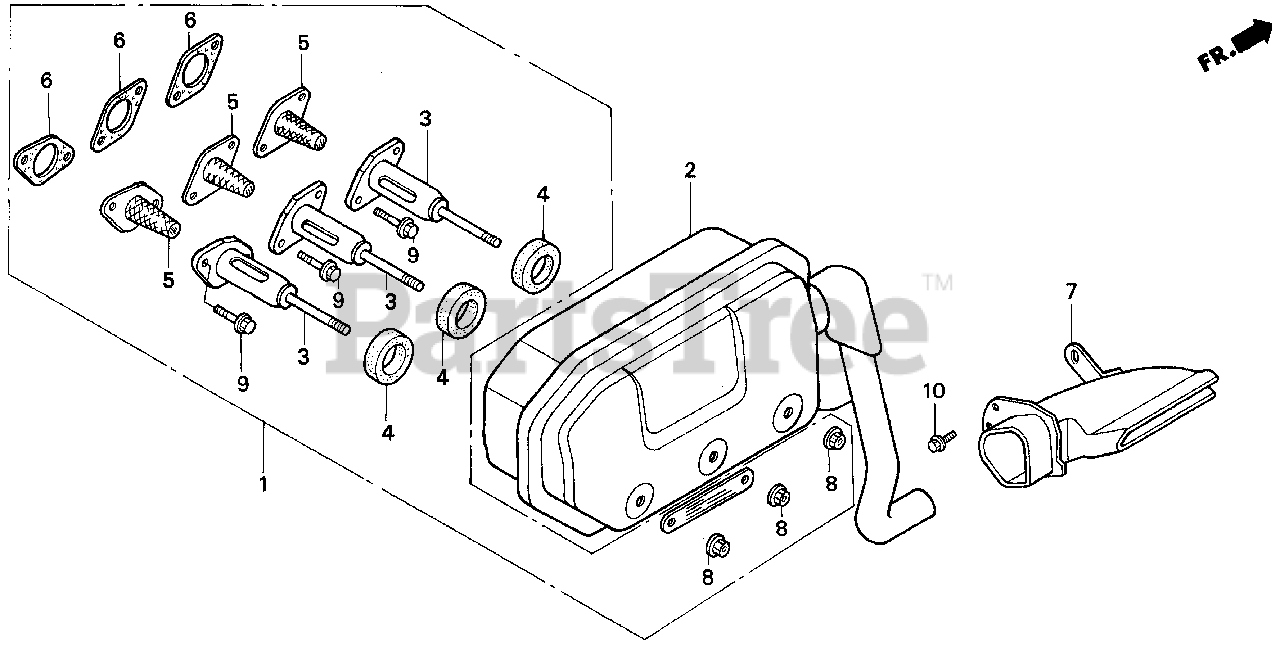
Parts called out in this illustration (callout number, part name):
1	ARRESTER KIT, SPARK
4	GASKET, EX. PIPE
5	ARRESTER, SPARK
6	GASKET, MUFFLER
7	DEFLECTOR, EX.
8	NUT, SELF-LOCK (10MM)
9	BOLT-WASHER (8X28)
9	BOLT-WASHER (8X25)
10	BOLT, FLANGE (6X10)
